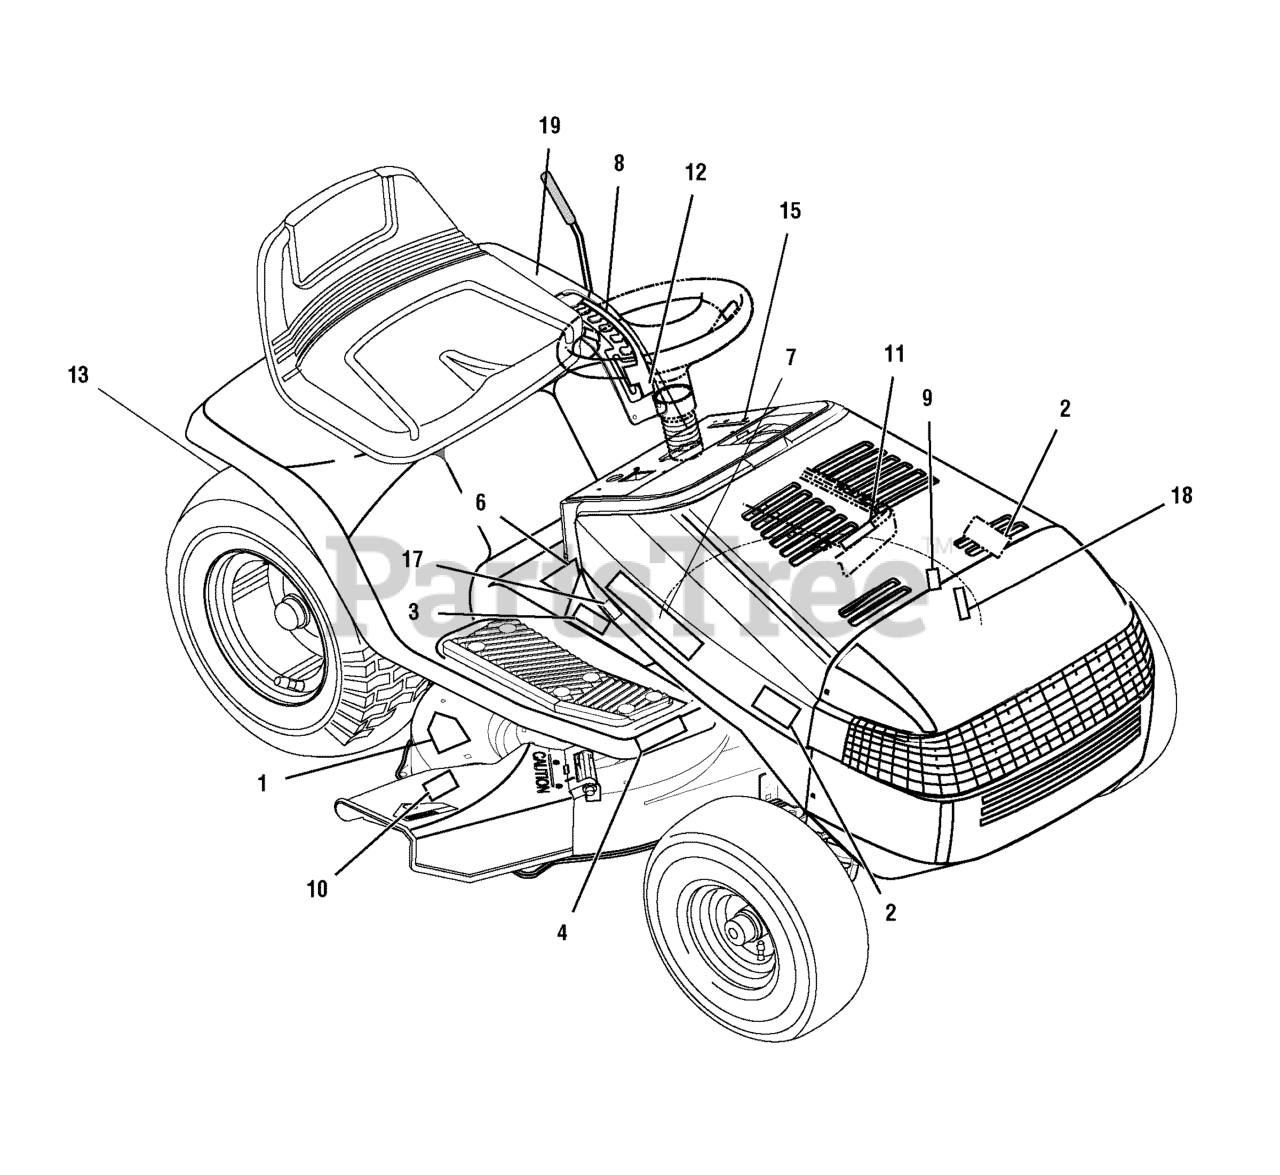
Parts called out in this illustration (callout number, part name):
1	DECAL, Cut Finger, English
2	DECAL, 18/42 R.H. & L.H.
3	DECAL, Briggs Logo
4	DECAL, 5 Speed
6	DECAL, Warning
7	DECAL, Murray Logo
8	DECAL, 1/6 Height Adjust Lift
9	DECAL, No Step, L.H. Housing
10	DECAL, No Step, Chute
11	DECAL, Clutch/Brake, Silver
12	DECAL, Deck Level Position Only
13	DECAL, Warning Load Limit
15	DECAL, Dash Symbols 3510
17	DECAL, V2-SS-1X3 Cutting Height
18	DECAL, 3-Way
19	DECAL, Engage PTO
